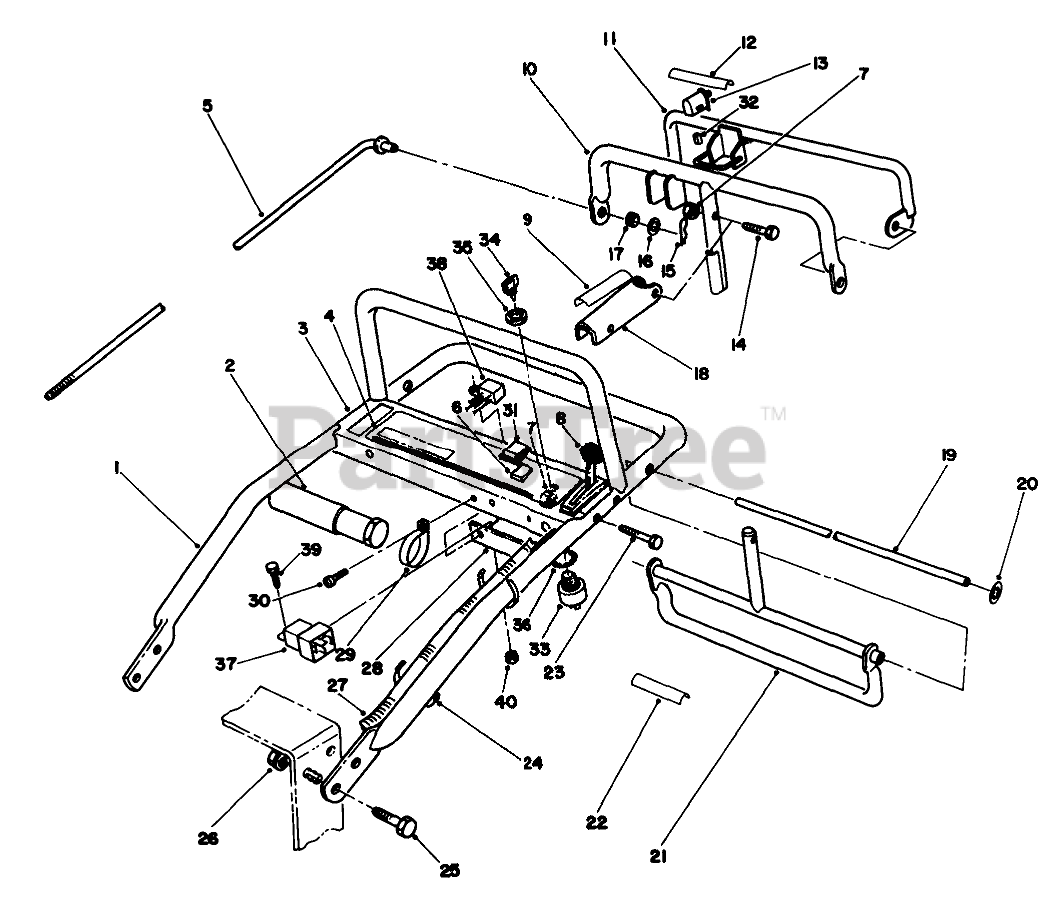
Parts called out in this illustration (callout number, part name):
1	Handle-Upper
2	TUBE-MANUAL
3	Panel-Control
4	DECAL - PANEL
5	ROD-CONTROL
6	SWITCH
7	NUT-LOCK, NI
8	Control-Throttle
9	DECAL-LEVER, PARKING
10	Bar
11	Bail
12	DECAL
13	SWITCH-BAIL
14	SCREW-SHH
15	PIN-COTTER
16	WASHER-FLAT
17	GROMMET-RUBBER
18	Lever-Parking Brake
19	PIVOT ROD
20	NUT-PUSH-ON, CIRCULAR
21	Control Pivot
22	DECAL
23	SCREW-SHH
24	TIE-CABLE
25	SCREW-HHF
26	NUT-HF
27	WIRE HARNESS
28	Panel-Bottom
29	CLAMP-R
30	SCREW-HWHTF
31	BOOT-SWITCH
32	CONNECTOR-BODY
33	Switch-On/Off (Incl. Ref. #34-36)
34	KEY-IGNITION
35	NUT-HH
36	WASHER-TOOTH, INTERNAL
37	RELAY
38	Module
39	SCREW-HH
40	NUT-LOCK, NI
